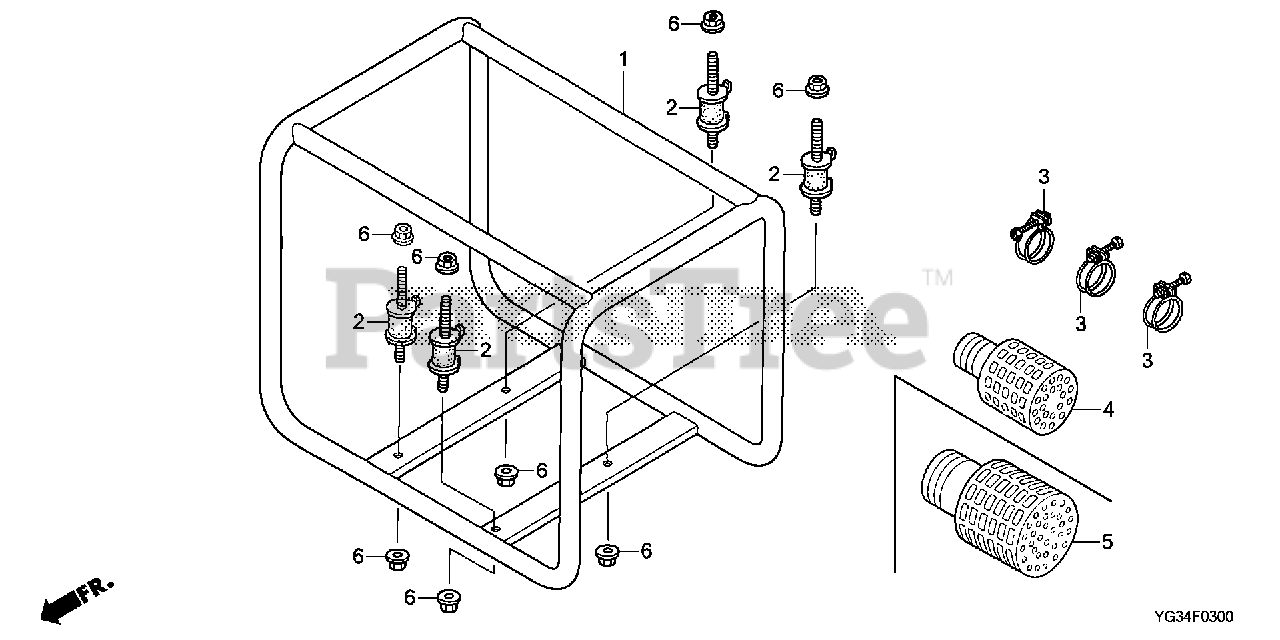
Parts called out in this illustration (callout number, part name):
2	RUBBER, ENGINE MOUNTING Use up to Frame SN 1382074.
3	BAND, HOSE
6	NUT, FLANGE (8MM)
